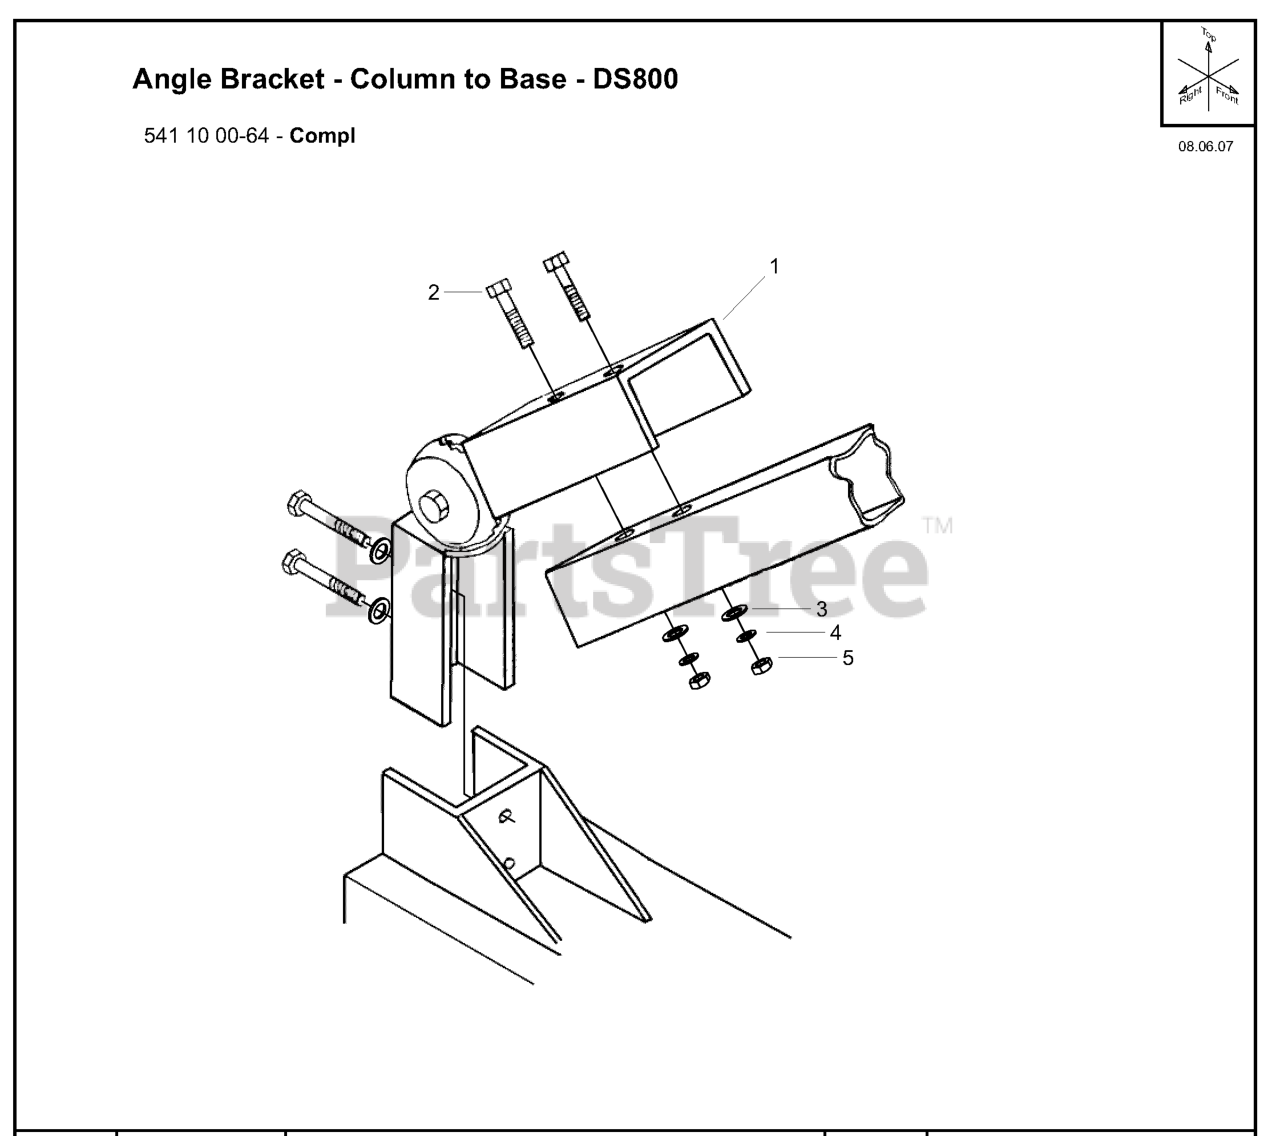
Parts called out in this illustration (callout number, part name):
1	Bracket, Angle
2	Capscrew, Hex Hd, M16-2.0 x 100 DIN931 8.8
3	Washer, Flat, M16 DIN126
4	Lockwasher, Split M16 DIN127
5	Nut, Hex M16-2.0
